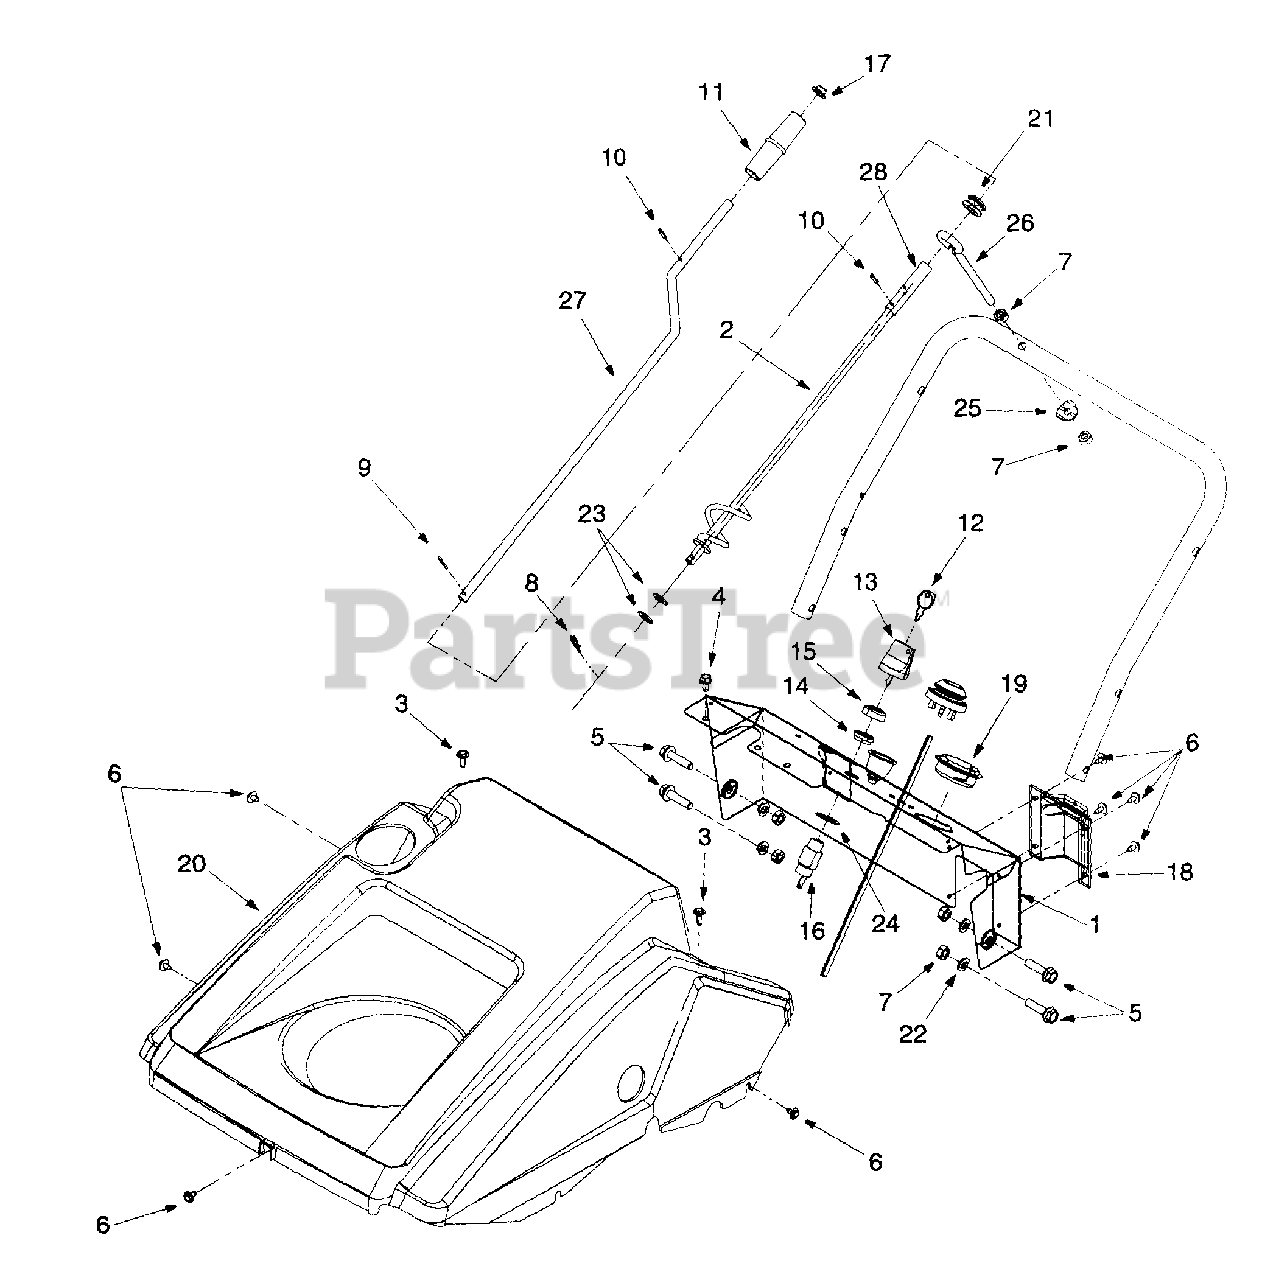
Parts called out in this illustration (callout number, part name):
1	Dash 21"
4	Screw-Hex
5	Flange
6	Screw-Hex
7	Nut-Hex
8	Cotter Pin
9	Cotter Pin
10	Pin Roll
11	Knob-Chute Crank
12	Key-Ignition Switch
13	Key-Ignition-Std
14	Ignition Switch Nut
15	Ignition Switch Cap
16	Ignition Switch
17	Cap-Push
18	Cover-Choke
19	Plug
20	Shroud
21	Grommet
22	Washer-Lock
23	Washer-Flat
24	Washer Internal Lock
25	Washer
26	Eyebolt Chute Crank
28	Spacer
